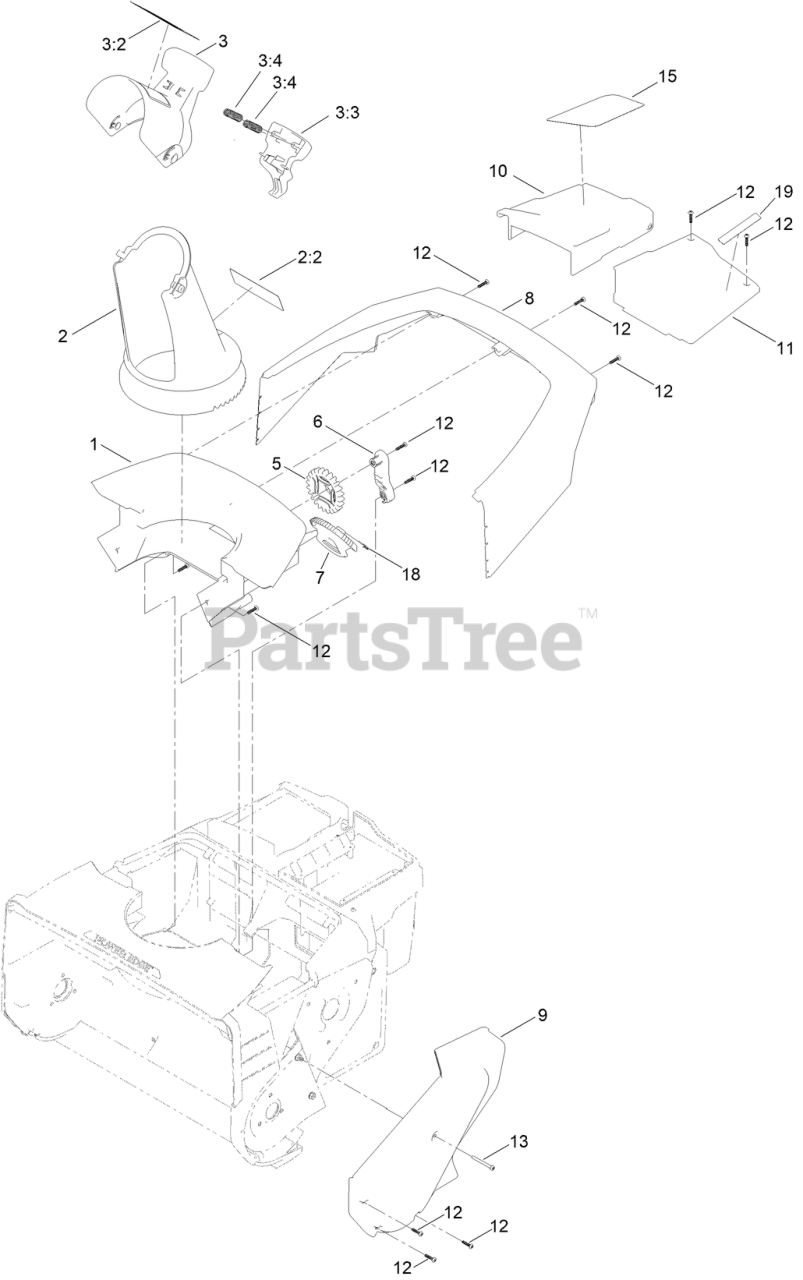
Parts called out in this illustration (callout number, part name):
1	CHUTE-REAR
2:2	DECAL-DANGER, DISCHARGE
3	DEFLECTOR-CHUTE
3:2	DECAL-DANGER
3:3	TRIGGER-DEFLECTOR
3:4	SPRING-COMPRESSION
5	GEAR-CHUTE
6	BRACKET-GEAR
7	GEAR-SECTOR
8	SHROUD
9	COVER-BELT
10	COVER-BATTERY
11	COVER-CONTROLLER
12	SCREW-PPH
13	SCREW-PLASTIC, PPH
15	DECAL-BATTERY, 60V SNOW
18	CLIP-HANDLE
19	DECAL-BRUSHLESS
